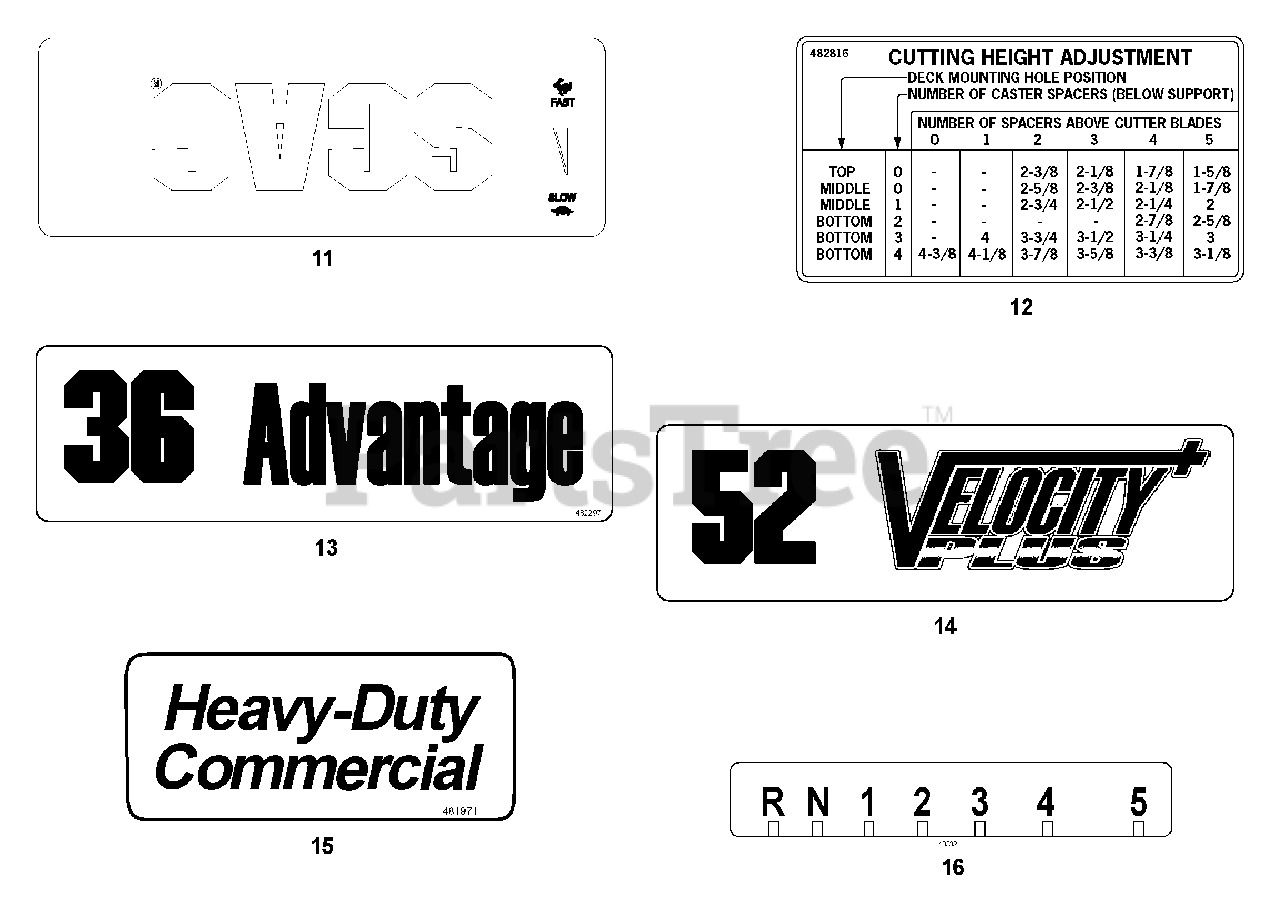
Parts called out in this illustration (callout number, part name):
11	Decal, Instrument Panel - Front
12	Decal, Height of Cut
13	Decal, 32
14	Decal, 48 Velocity Plus
15	Decal, Heavy Duty Commercial
16	Decal, Shift Index
